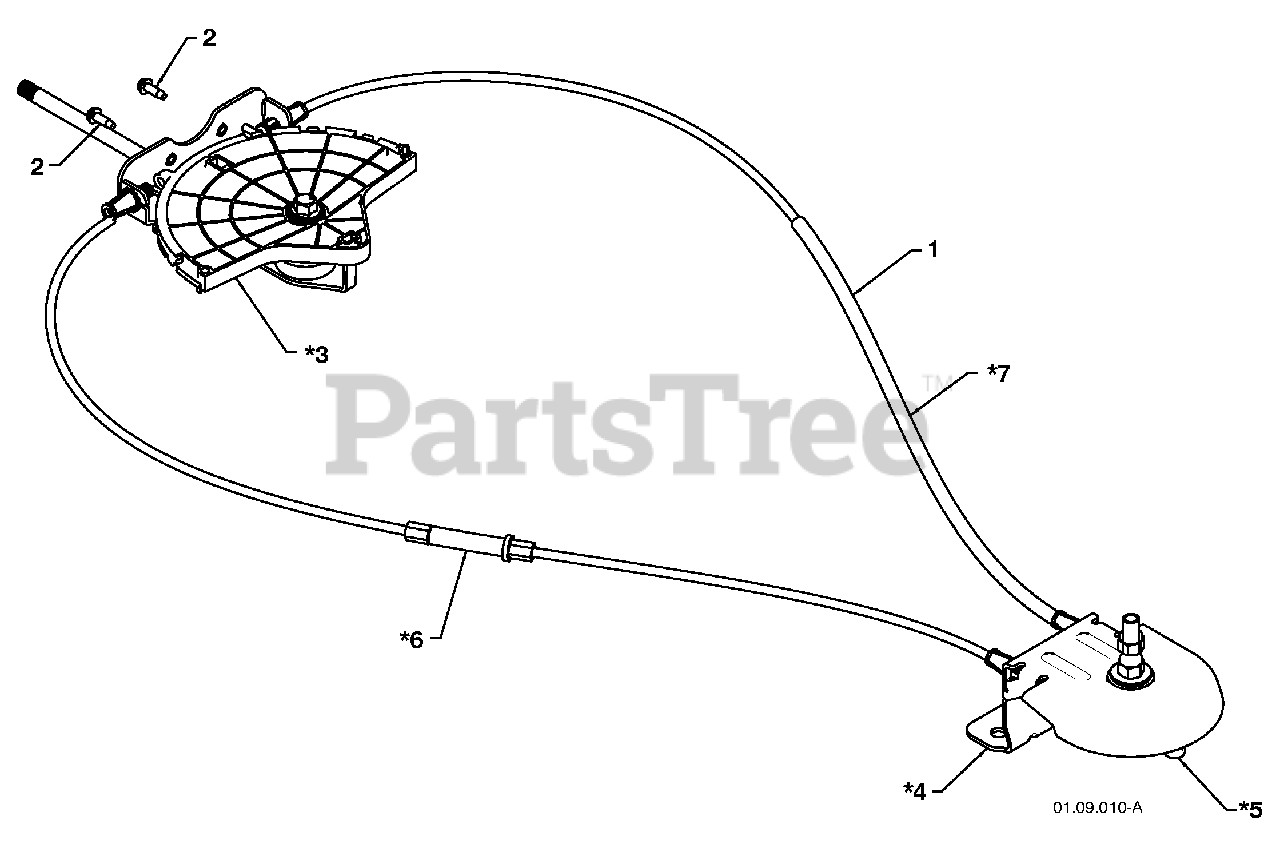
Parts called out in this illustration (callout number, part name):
1	LEVER/CABLE ROTATOR ASSEMBLY
2	SCREW 10-24 X .625
3	ROTATOR HEAD
4	ROTATOR PIVOT BRACKET
5	PULLEY PIVOT
6	CABLE ASSEMBLY ADJUSTABLE
7	CABLE ASSEMBLY HEAT SHIELD
